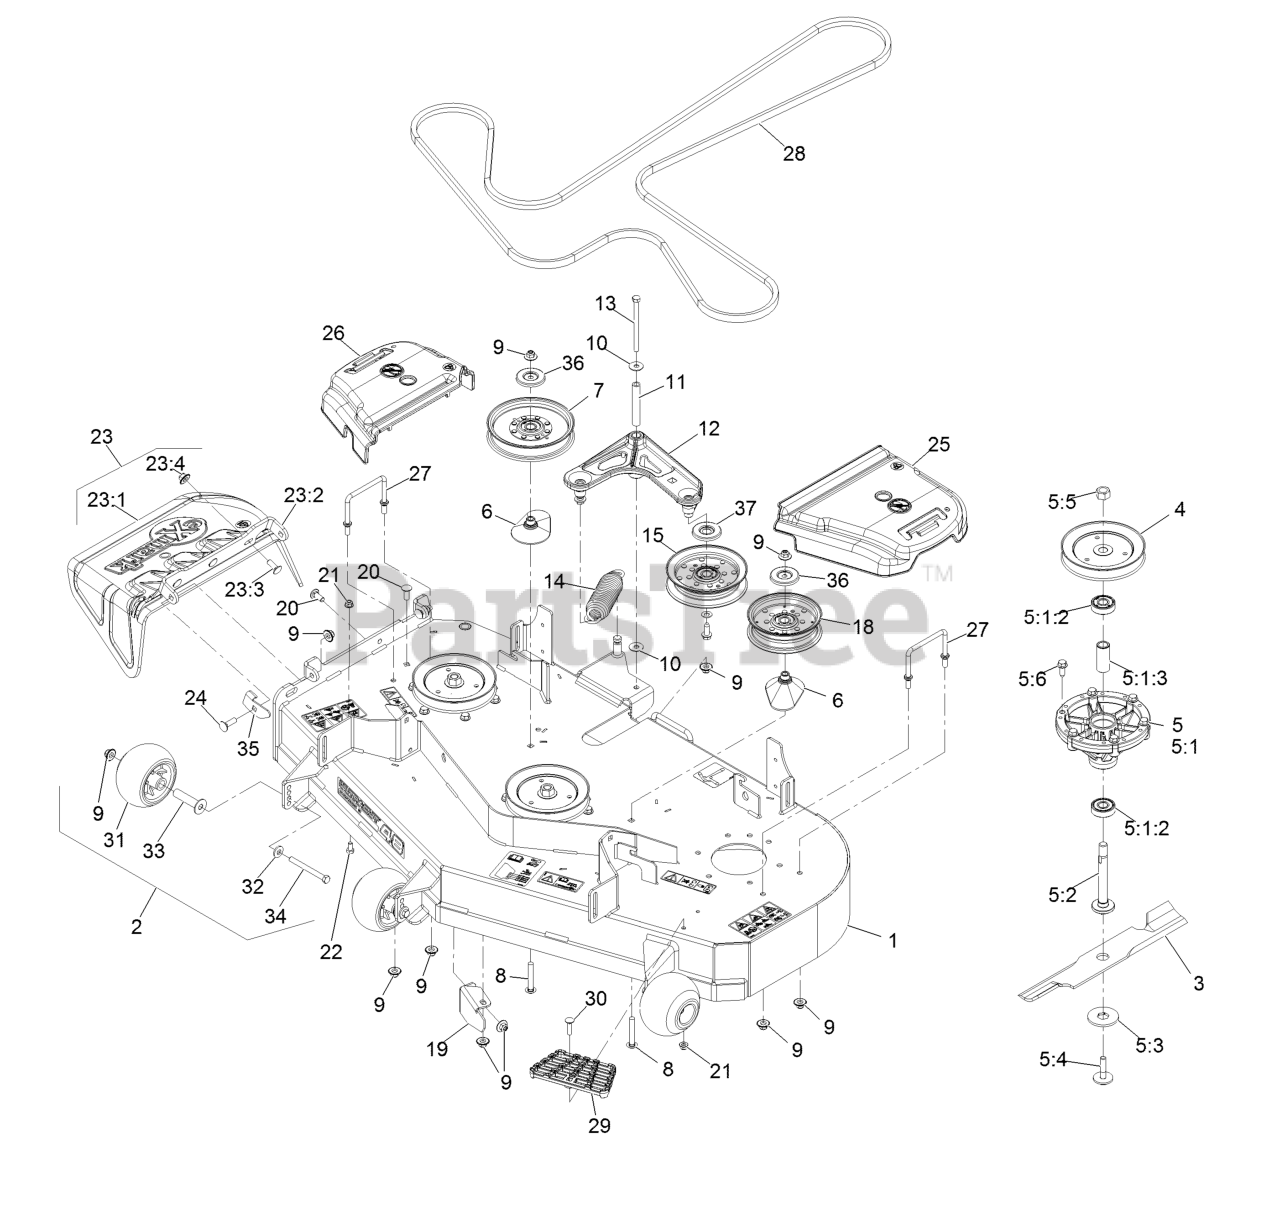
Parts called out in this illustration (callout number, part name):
1	ASM-Deck W/Decals 483
2	Kit, Anti-Scalp Roller
3	Blade, Mulching
3	Blade, Low Lift
3	Blade, Solid
3	Blade-Notched
3	Blade-Extreme 2, 16.25"
4	Sheave,Blade Drive 5.90
5	ASM, Cutter Housing Complete
5:1	ASM-Cutter Housing
5:1:2	Bearing
5:1:3	Spacer-Bearing
5:2	Spindle-Hex Pilot
5:3	Washer-Hex Blade Drive
5:4	Bolt-Blade, Sem
5:5	Nut-Hex 5/8-18
5:6	Screw-Forming, Thread
6	Spacer-Pulley
7	Idler-Pulley, Flat 6.00X1.00
8	Bolt-Carriage 3/8-16 X 2 1/2
9	Nut-Nyloc 3/8-16 Flg
11	Bushing
12	Idler Arm ASM
13	Screw-HH 3/8-16 X 4 3/4
14	Spring-Extension
15	Idler-Pulley, Flat
18	Idler-Pulley, Flat 5.00X1.31
19	Baffle,Discharge 483
20	Bolt-Carriage 3/8-16 X 1
21	Nut-Nyloc 5/16-18 Flg
22	Screw-HH 5/16-18 X 5/8
23	ASM,Discharge Chute
23:1	Chute, Discharge
23:2	Bracket,Discharge Chute
23:3	Bolt-Carriage 3/8-16 X 1
23:4	Nut-Nyloc 3/8-16 Flg
24	Bolt-Carriage 3/8-16 X 1 1/4
25	Cover-Belt, LH
26	Cover-Belt, RH
27	Wireform-Cover
28	Belt-V
29	Step-Deck
30	Bolt-Carriage 5/16-18 X 1 1/4
31	Roller-Anti-Scalp
32	Washer-Spring Disc 3/8
33	Axle, Roller
34	Screw-HH 3/8-16 X 3 3/4 GR 8
35	Stop-Discharge Chute
36	Shield-Dust
37	Shield-Guard, Dust
